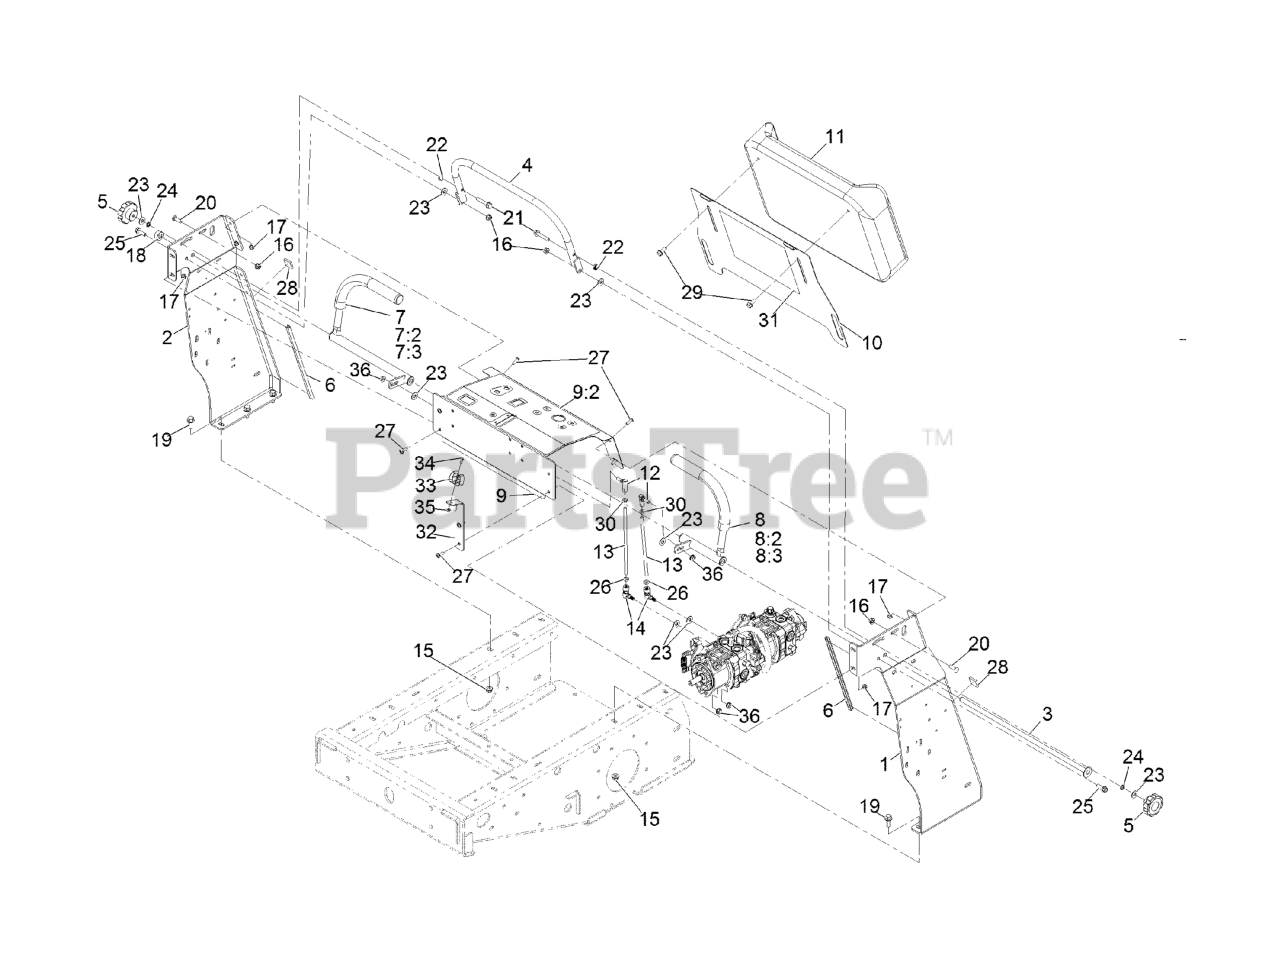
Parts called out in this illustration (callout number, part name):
1	Upright-Tower, Lt
2	Upright-Tower, Rt
3	Rod-Pivot, Joy Stick
4	Bar-Speed
5	KNOB-FLUTED
6	STRIP-TRIM, 12.0"
7	Stick-Joy, Rt
7:2	GRIP-CONTROL, MOTION
7:3	BUSHING-FLANGE
8	Stick-Joy, Lt
8:2	GRIP-CONTROL, MOTION
8:3	BUSHING-FLANGE
9	Panel-Control
9:2	DECAL-CONTROL PANEL
10	PLATE, KNEE PAD
11	Pad-Knee, Z-Spray/Z-Plug
12	Balljoint-SS
13	ROD-CONTROL, MOTION
14	Ball Joint-Quick Disconnect, SS
15	Nut-Hex Flange
16	Nut-Hex Flange
17	Nut-Hex Flange
19	SCREW-HHF
20	Bolt,Carriage,5/16-18X1,ST/ST 18-8
21	Screw-HHF
22	Nut,Hex Flange,5/16-18,Sst, Rie2006
23	FLAT WASHER, 5/16 NOM,ST
24	Washer-Lock
25	SCREW-HHF
26	Nut-Hex
27	Screw-Hsbhf
29	SCREW-HHF
30	Nut-Hex
31	DECAL-SPRAY CHART
32	Mount-Gun
33	Holder-Tool, Clip
34	Screw-HSBH
35	Nut-Hex Flange
36	Nut-HHF
